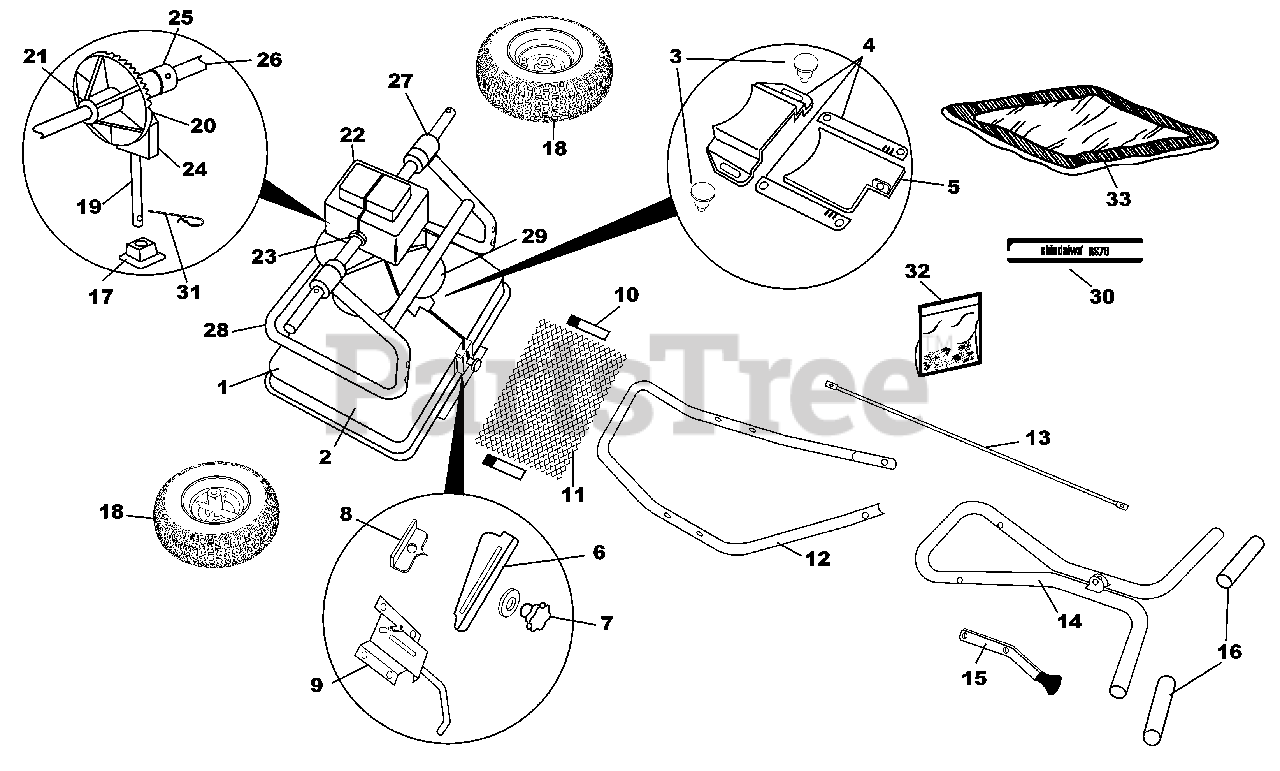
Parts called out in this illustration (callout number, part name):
1	Hopper Assembly
2	Hopper
3	Discharge Chute Knob
4	Discharge Chute & Shut-Off Plate Guides
5	Shut-Off Plate
6	Rate Plate
7	Rate Control Knob
8	Pointer
9	Spring Housing Assembly
10	Screen Clips
11	Hopper Screen
12	Handle Brace/Leg
13	Control Tube
14	Upper Handle
15	Handle Lever Assembly
16	Handle Grip
17	Impeller Shaft Bearing
18	Drive Wheel
19	Impeller Shaft
20	Pinion Gear
21	Axle Gear
22	Gear Cover
23	Gear Cover Clamps
24	Gear Support
25	Axle Collar w/Set Screw
27	Axle Bearing
28	Frame Assembly
29	Impeller
30	Free Wheel
31	Agitator
32	Fastener Package
33	Hopper Cover
34	Hopper Label
